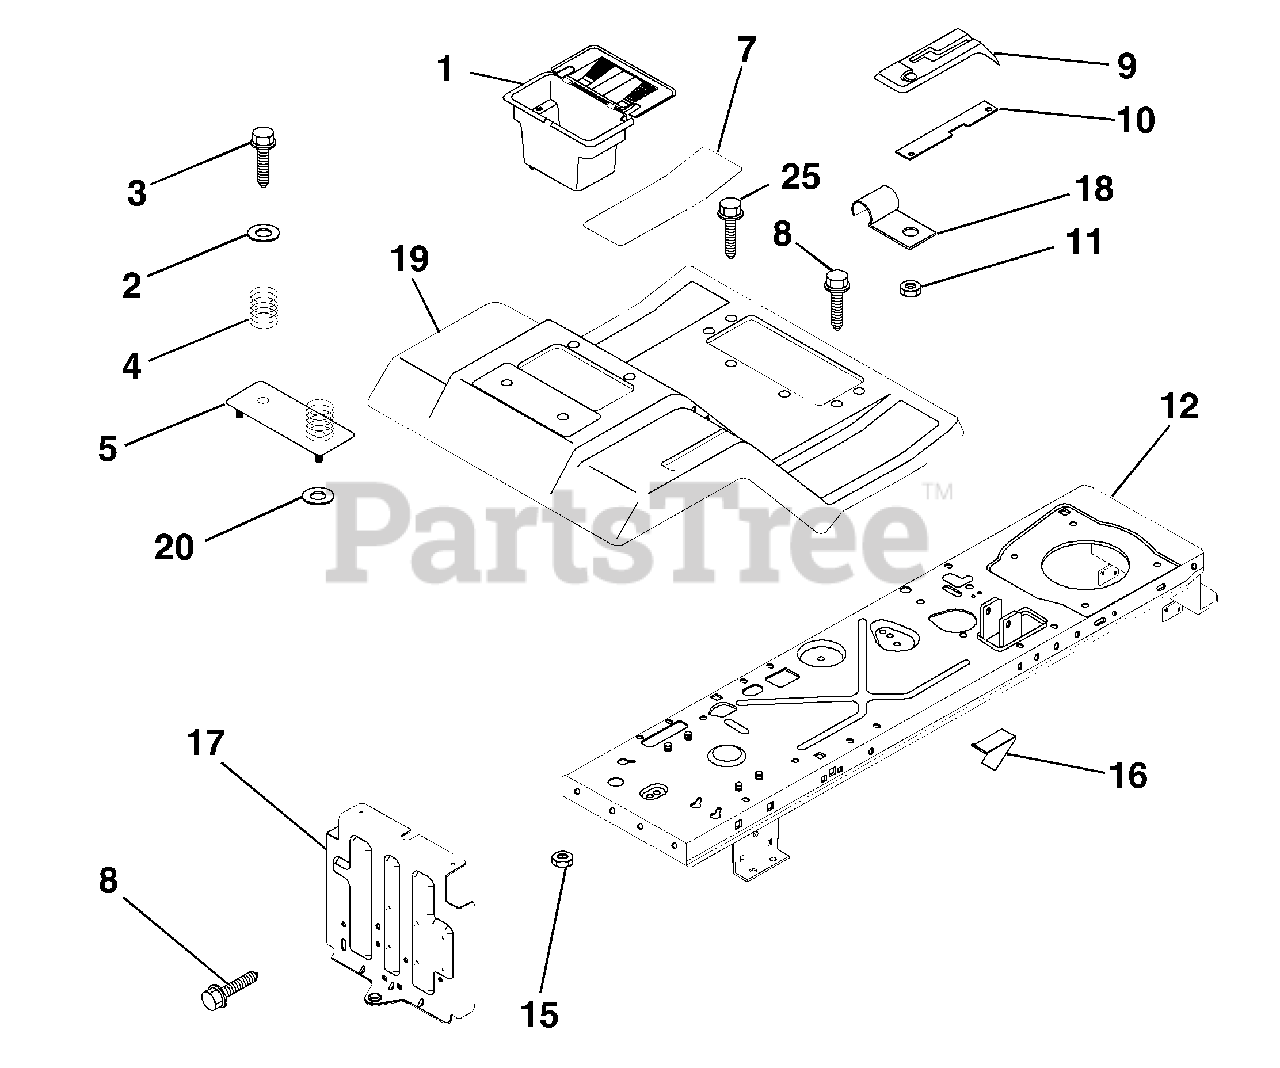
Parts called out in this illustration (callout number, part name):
1	Case, Battery
2	Washer 13/32 x 1-1/4 x 12 Ga.
3	Screw, Hex Wsh. Thrdrol 3/8-16 x 3/4
4	Spring, Compression, Seat
5	Plate, Asm. Battery
7	Pad, Footrest
8	Screw, Thdrol 5/16-18 x 3/4
9	Console, Shift Control
10	Bar, Shift Lock
11	Nut, Self-Threading, Wsher Hd 3/16
12	Assembly, Frame
15	Nut, Keps 1/4-20 UNC
16	Switch, Actuator
18	Clip, Insulated
19	Fender/Footrest
20	Washer 9/32 x 7/8 x 13 Ga.
25	Screw Hex 5/16-18 Unc x1
